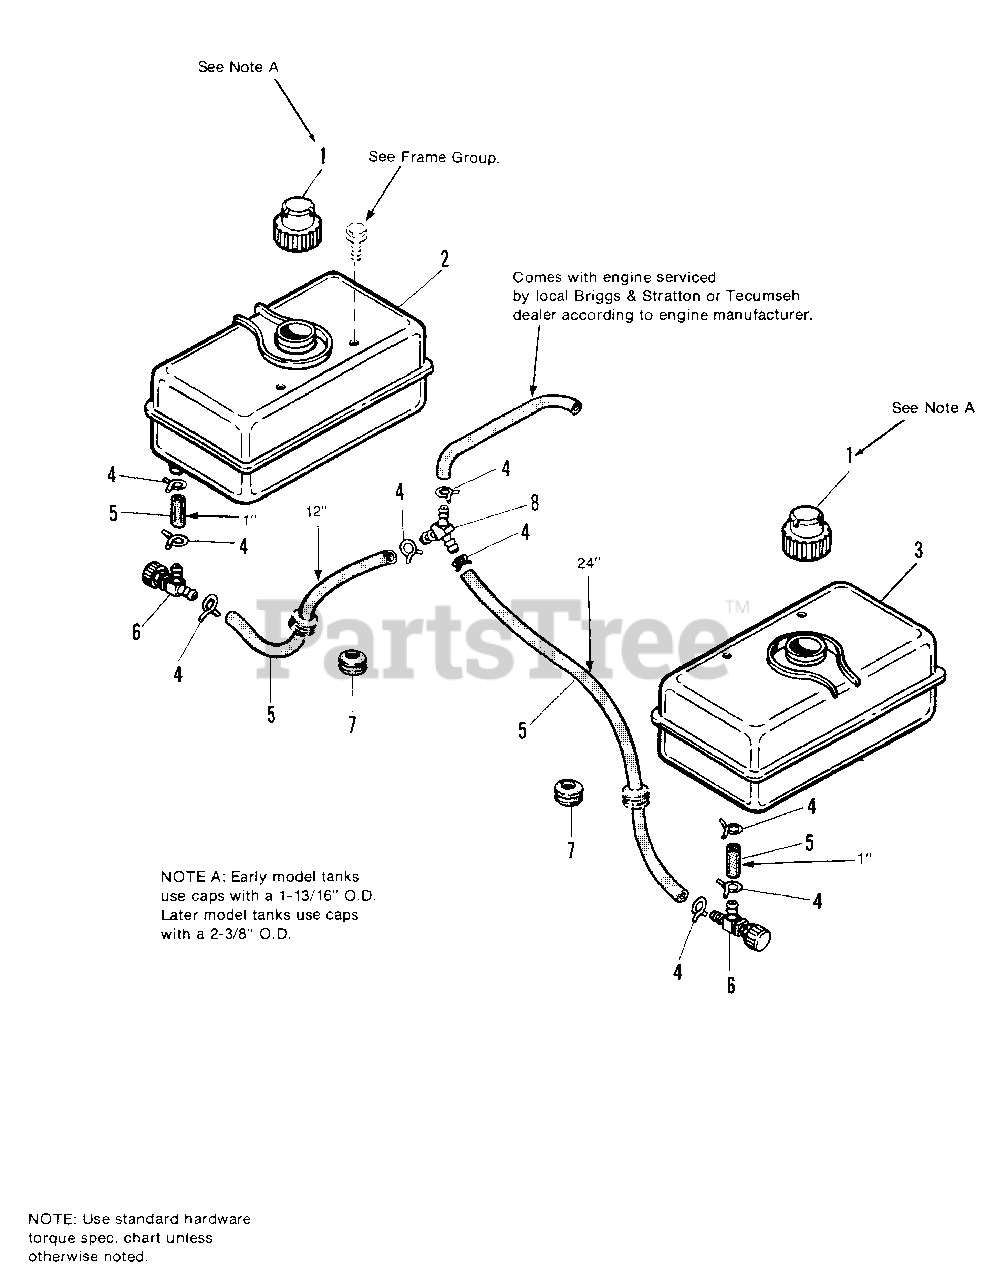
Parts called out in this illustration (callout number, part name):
1	CAP, Fuel Tank (Later Models 2-3/8" O.D.)
1	CAP, Fuel Tank (Earlier Models 1-13/16" O.D.)
2	TANK, Fuel (R.H.)(Incl. Cap Part No. 1702507)
3	TANK, Fuel (L.H.)(Incl. Cap Part No. 1702507)
4	CLAMP, Hose
5	HOSE, Fuel, 45-1/2" (cut toHOSE, Fuel, Cut to 12th)
6	VALVE, Shutoff
8	FITTING, Tee
